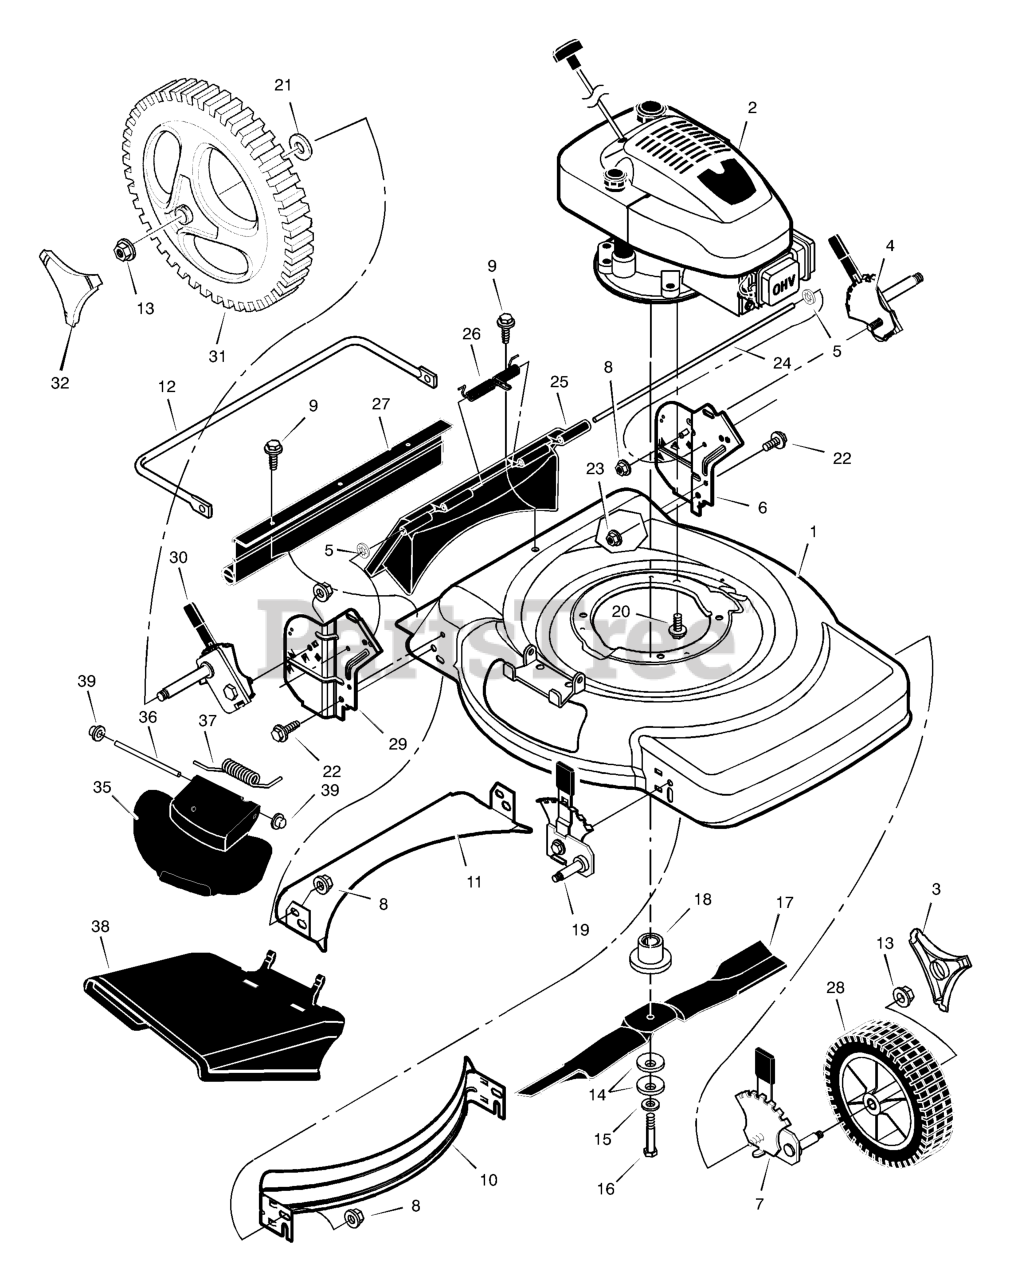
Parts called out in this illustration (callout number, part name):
2	Engine *
3	Cap, Hub
4	Adjuster, Left Rear Height
5	Retainer, Push
6	Bracket, Left Handle
7	Adjuster, Left Front Height
8	Nut, Flange
10	Baffle, Front
11	Baffle, Rear
13	Nut, Flange
14	Washer, Belleville
18	Adapter, Blade
19	Adjuster, Right Front Height
20	Bolt, Engine
22	Bolt
23	Nut, Flange
24	Rod, Pivot
25	Door, Rear (Black)
26	Spring
27	Guard, Rear
28	Wheel & Tire, Front
29	Bracket, Right Handle
30	Adjuster, Right Rear Height
31	Wheel & Tire, Rear
32	Cap, Hub
35	Cover, Mulch (Black)
36	Rod, Pivot
37	Spring, Torsion
38	Deflector, Chute (Black)
39	Push On Cap
